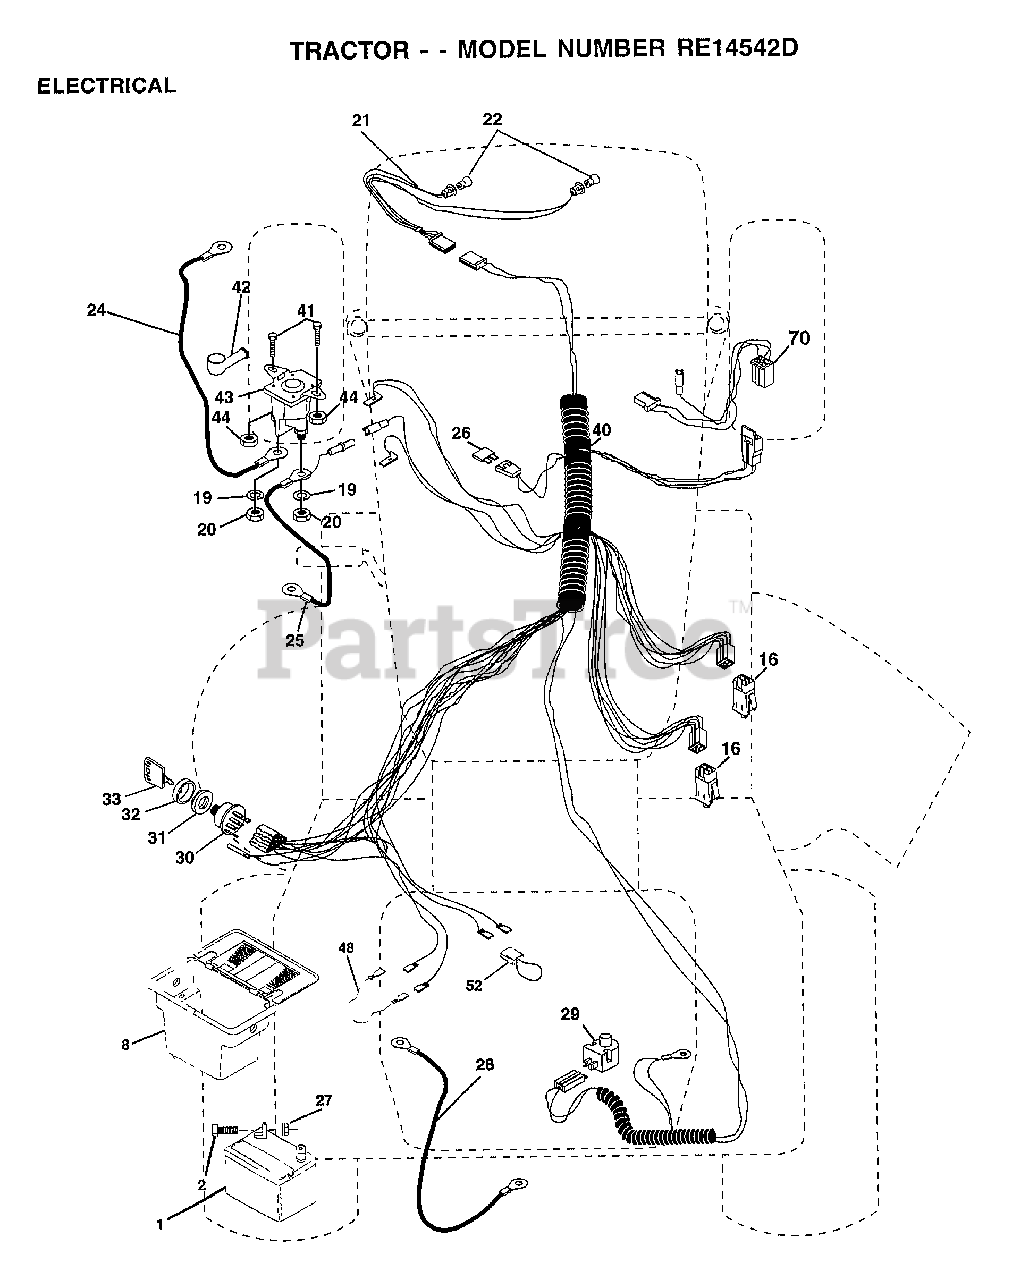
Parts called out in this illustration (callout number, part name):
2	BOLT LT
8	"CASE,BATTERY.MECH"
16	SWITCH INTERLOCK
20	NUT
21	HARNESS.ASM.LIGHT W/4152J
22	HEADLAMP BULB
24	"CABLE T, BATTERY"
25	CABLE.BTRY.6GA.RD
26	FUSE.15 AMP
27	NUT
28	CABLE T
29	SWITCH SEAT
30	SWITCH IGN 4POS
31	NUT IGNITION
32	COVER KEY SWITCH
33	KEY
40	HARNESS.IGNITION
41	BOLT HXHD FIN
44	NUT HXKEP 1/4X20
48	ADAPTER AMMETER
52	PROTECTION LOOP
70	HARNESS.ENGINE
